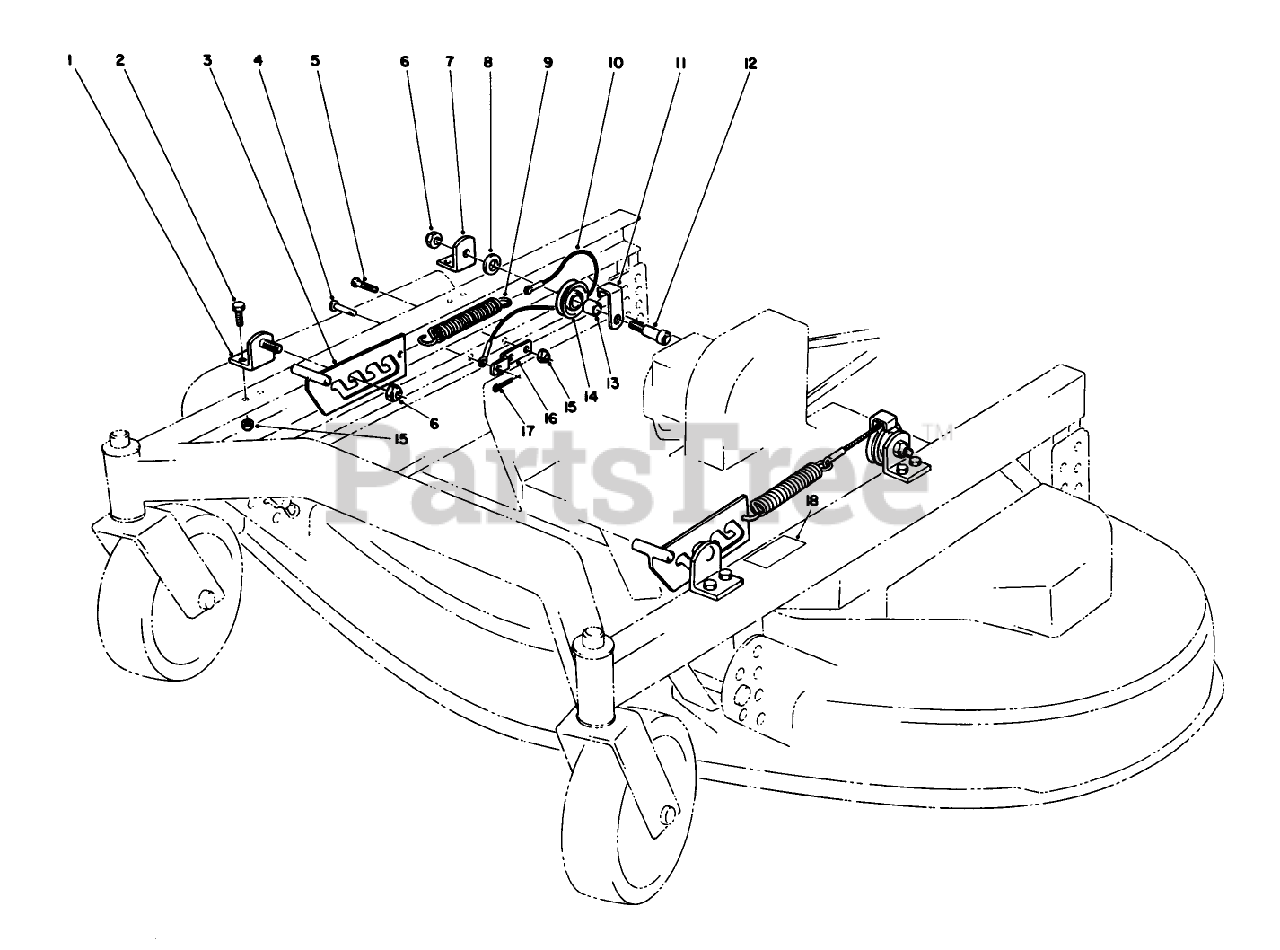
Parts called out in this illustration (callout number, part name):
2	SCREW-HH
5	1/4-20 X 5/8 RD HD SC
6	NUT-LOCK, NI
9	EXTENSION SPRING
10	CABLE
13	BUSHING
15	NUT-LOCK, NI
18	DECAL-WARNING
